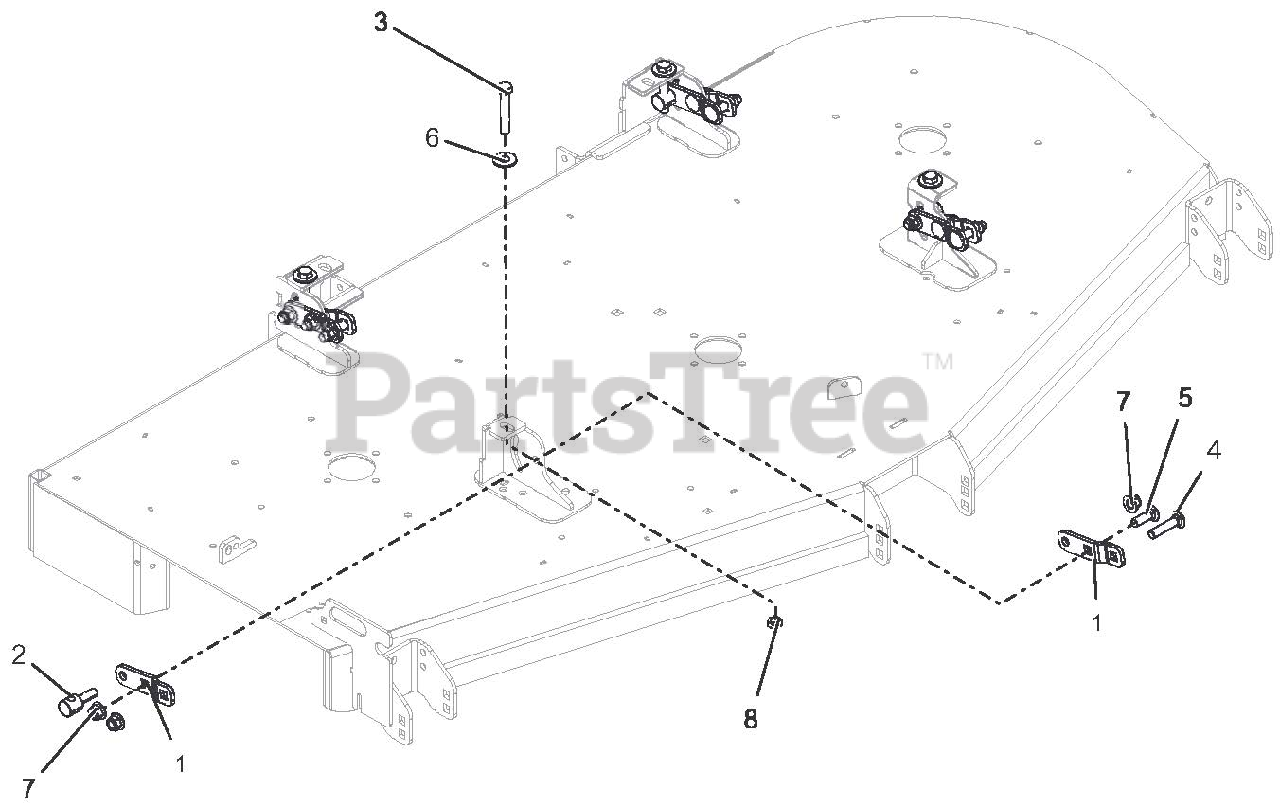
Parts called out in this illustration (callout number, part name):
1	BRKT, DECK LEVELING
2	TRUNNION, .50-13
3	BLT-HEX .50-13 X 3.00 GR5 FTH YWZC
4	BLT-RDHDSQNK .50-13 X 2.25 G5 Y
5	BLT-RDHDSQNK .50-13 X 1.50 G5 YWZC
6	WSHR-FL-STL .563 X 1.38 X .109YWZC
7	NUT-LK-NYL-FLG .50-13 YWZC
8	NUT, JAM .500-13 YWZC
